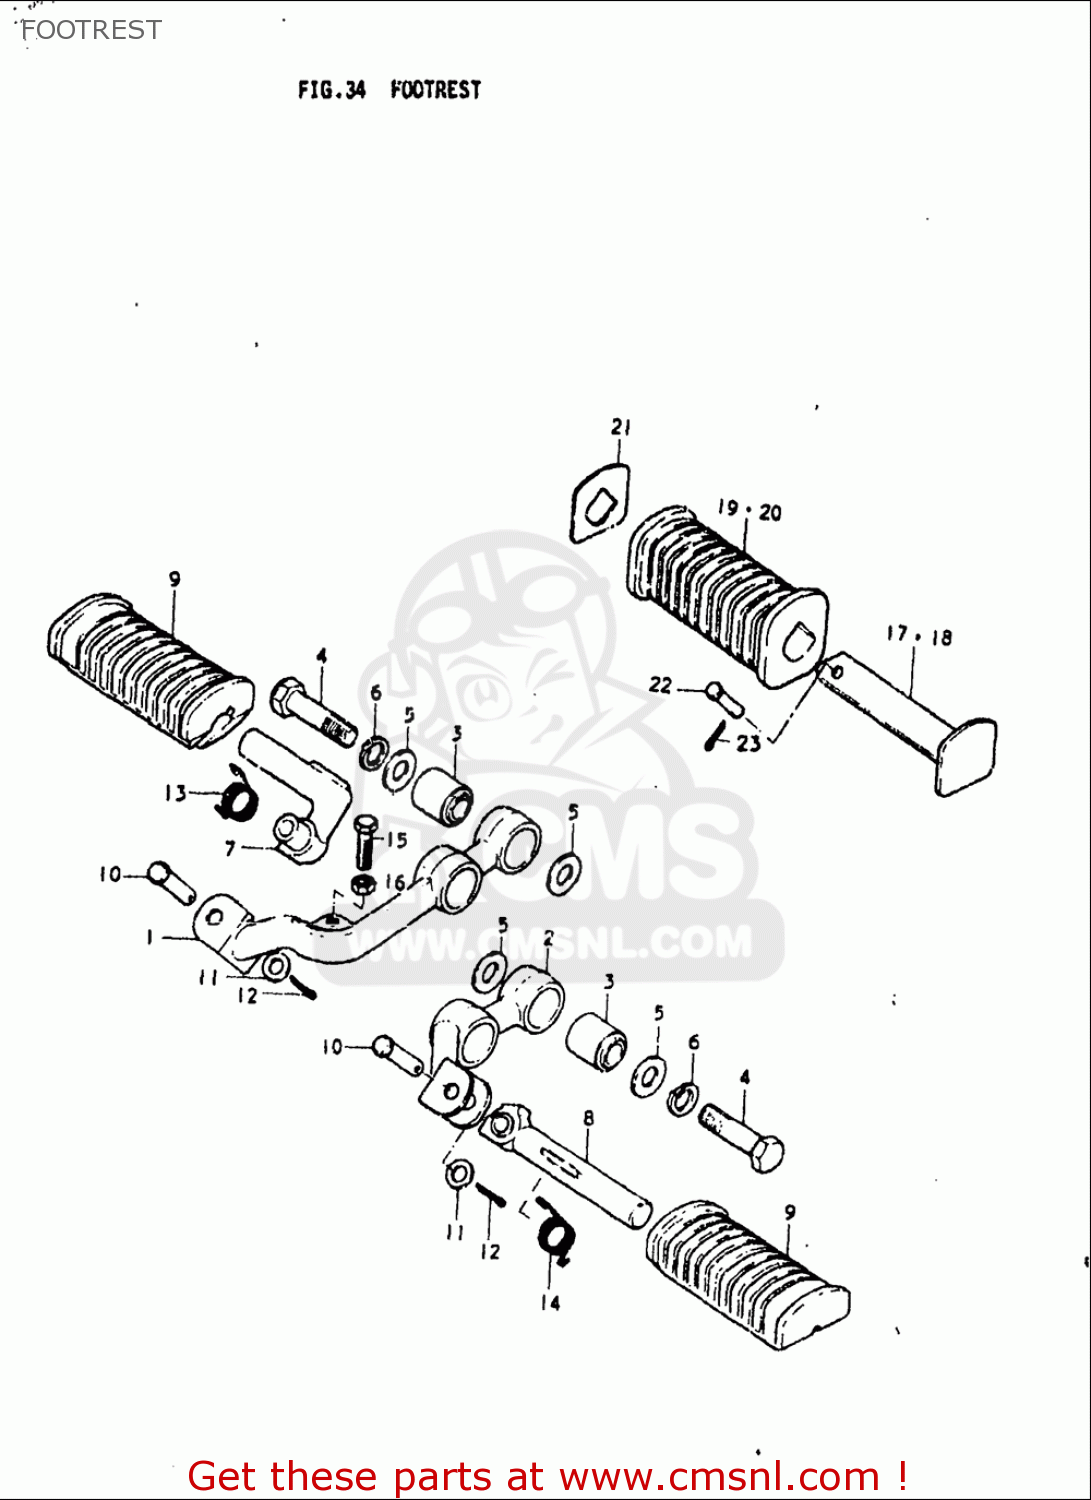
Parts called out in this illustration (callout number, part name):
3	BUSH
4	BOLT(10X38)
5	WASHER(10.5X20X2.3)
6	WASHER,LOCK
7	BAR,FRONT FOOTREST,RIGHT NO
9	RUBBER,FR FOOTREST
11	WASHER
12	PIN
13	SPRING
14	SPRING
15	BOLT
16	NUT 6MM
19	RUBBER,PILLION FOOTREST
20	RUBBER,PILLION FOOTREST
21	WASHER,PILLION FOOTREST RUBBER
22	PIN
23	PIN
